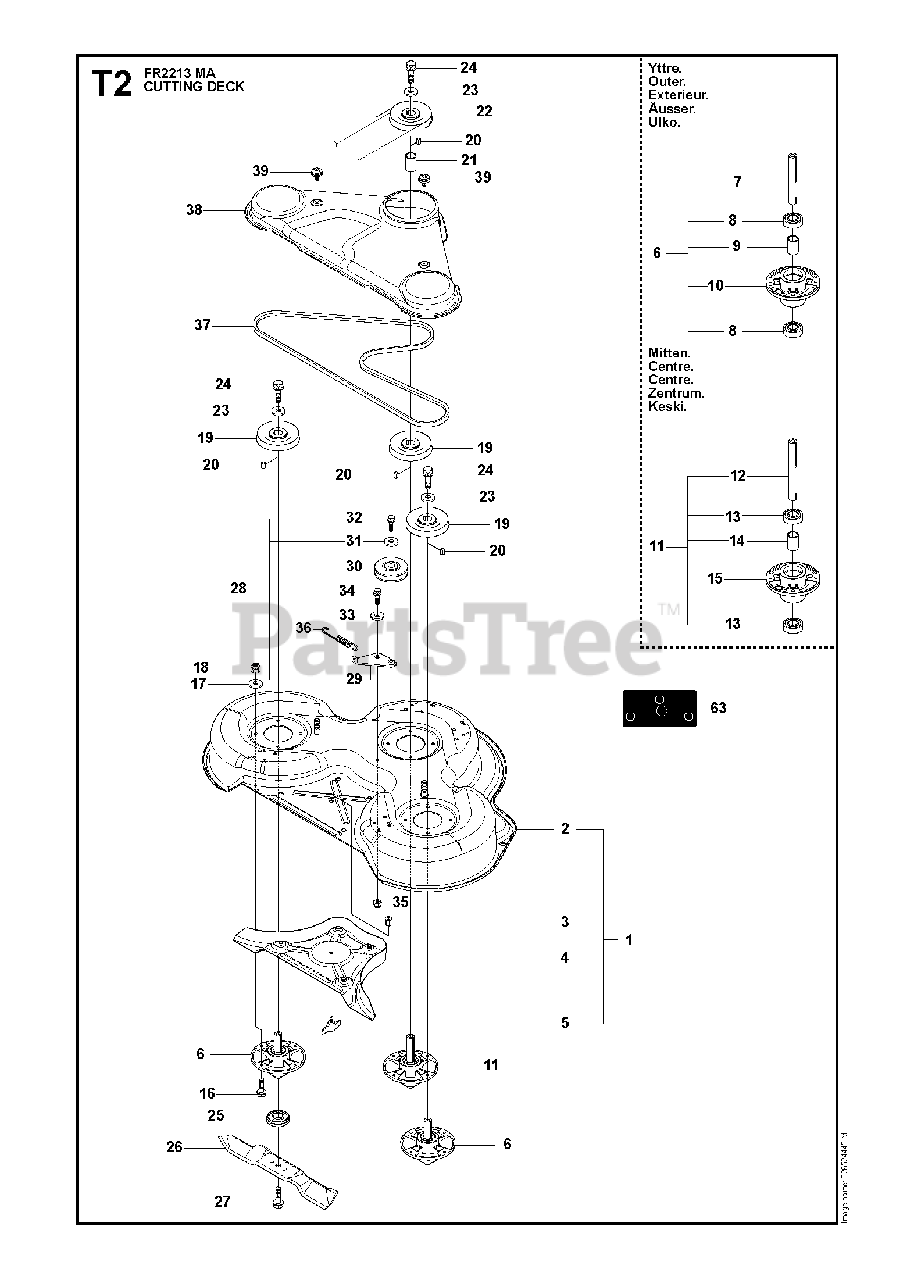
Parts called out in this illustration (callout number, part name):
3	NUT
6	RP SPINDLE ASSY
7	SHAFT
8	BEARING
9	SPACER
10	BEARING HOUSING
13	BEARING
14	SPACER
15	BEARING HOUSING
16	BOLT
17	WASHER BRB 8.4X17
18	LOCKNUT M8
19	PULLEY
20	KEY
22	PULLEY
23	WASHER
24	BOLT
27	BOLT
29	BRACKET
30	PULLEY
31	SPACER
32	BOLT
33	WASHER
34	SCREW
35	LOCKNUT M8
36	SPRING
39	SCREW
42	BEARING
43	PLATE
45	BRACKET
47	BOLT
48	LOCKNUT M8
52	NUT
53	NUT
57	E-RING
58	BOLT
59	LOCKNUT M8
60	DECK ROLLER, FRONT
61	WASHER
62	RETAINING RING SGA 15
63	DECAL
